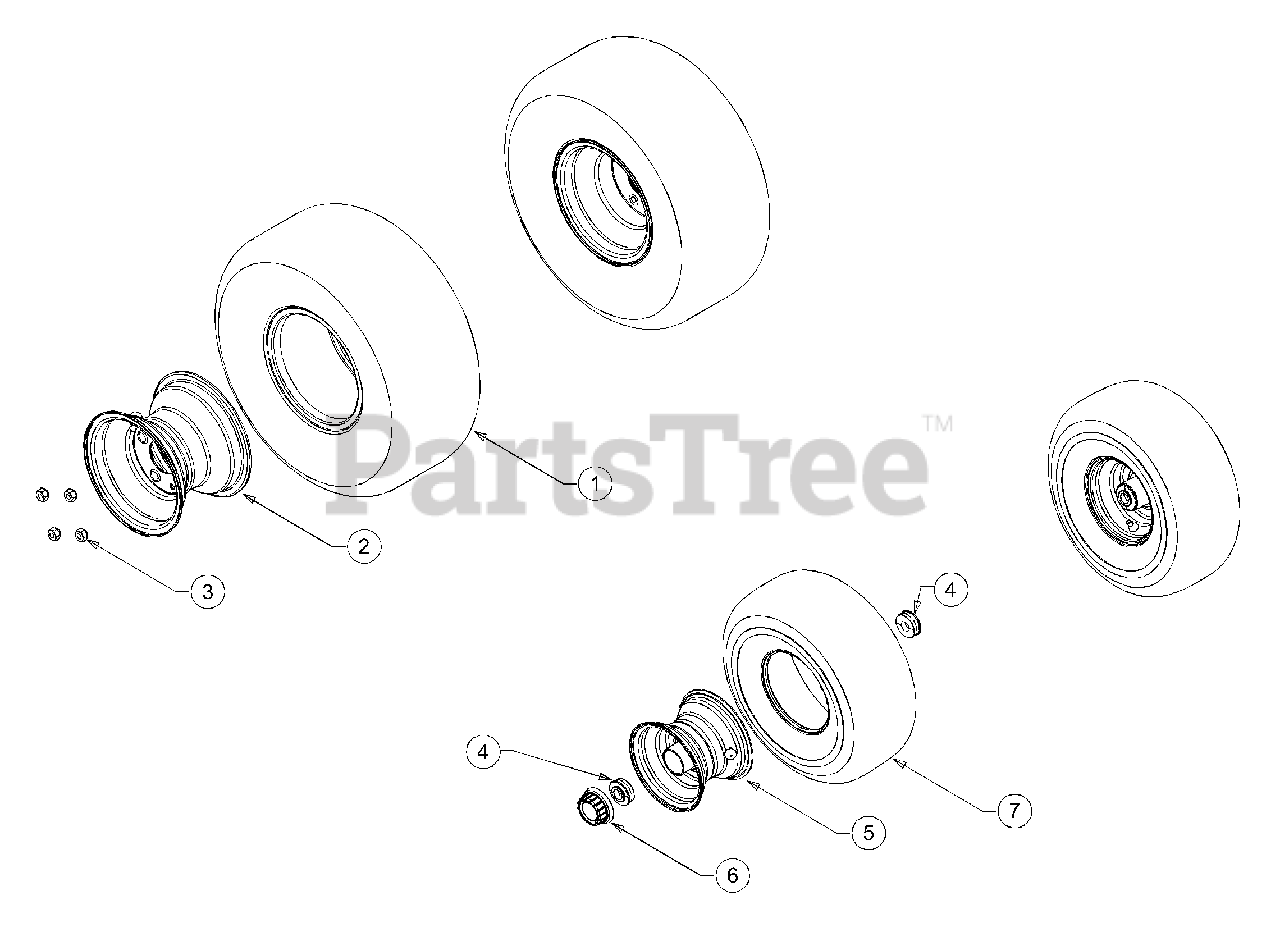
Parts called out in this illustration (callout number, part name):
1	Tire, Turf,Cub Cadet 20 x 9 x 8
3	Lug Nut, 7/16-14
4	Bearing, Ball, .75 ID x 1.75 OD
6	Hub Cap
7	Tire, Turf,Cub Cadet 15 x 6 x 6
